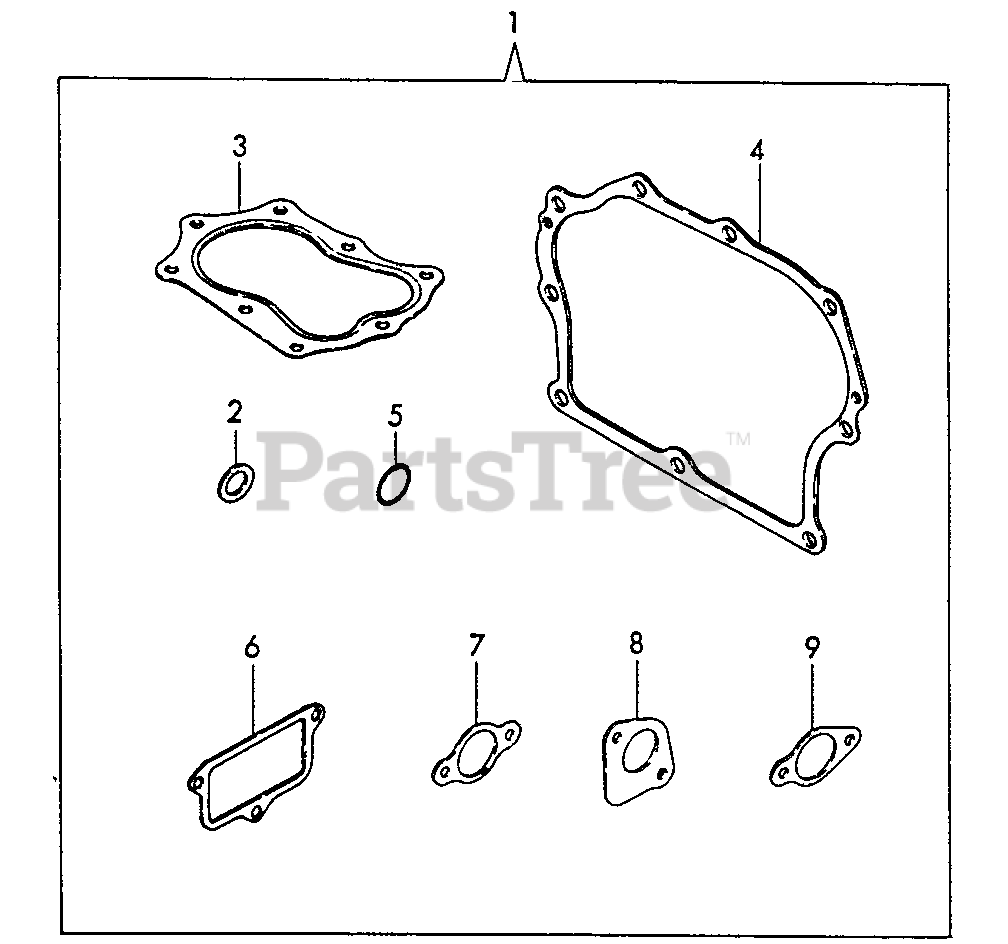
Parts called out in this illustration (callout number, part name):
1	GASKET KIT
2	GASKET
3	GASKET, CYLINDER
4	GASKET, CRANKCASE
5	O-RING - 18
6	GASKET, BREATHER
7	GASKET, INTAKE
8	GASKET, EXHAUST
9	GASKET, INTAKE
